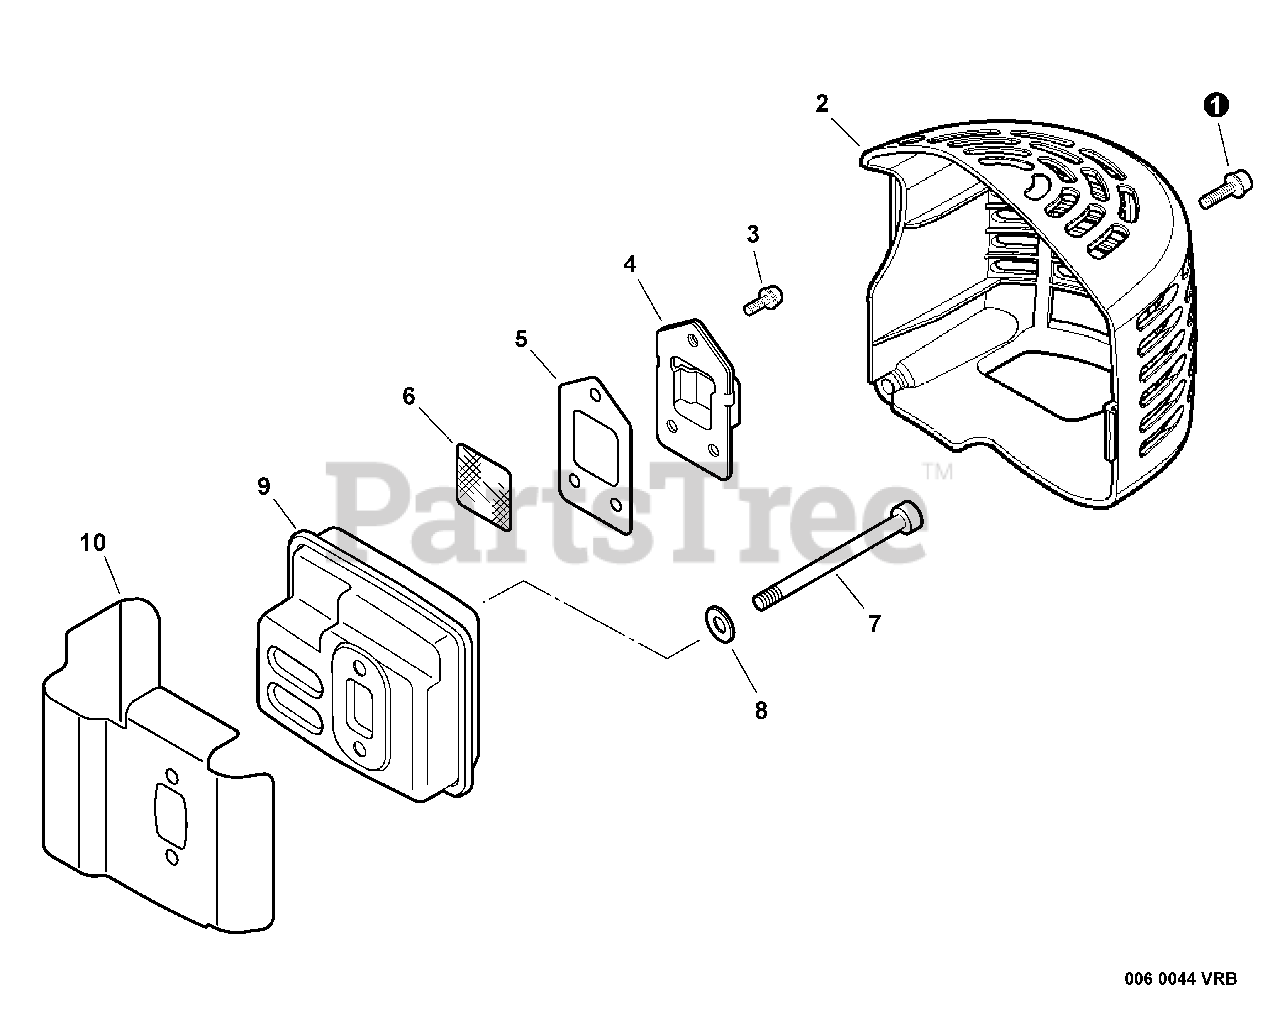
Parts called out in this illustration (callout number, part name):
1	SCREW - 5X16
2	COVER, EXHAUST
3	SCREW - 4X10
4	GUIDE, EXHAUST
5	GASKET, EXHAUST
6	SCREEN, SPARK ARRESTOR
7	SCREW - 5X55
8	WASHER - 5
10	SHIELD, EXHAUST
